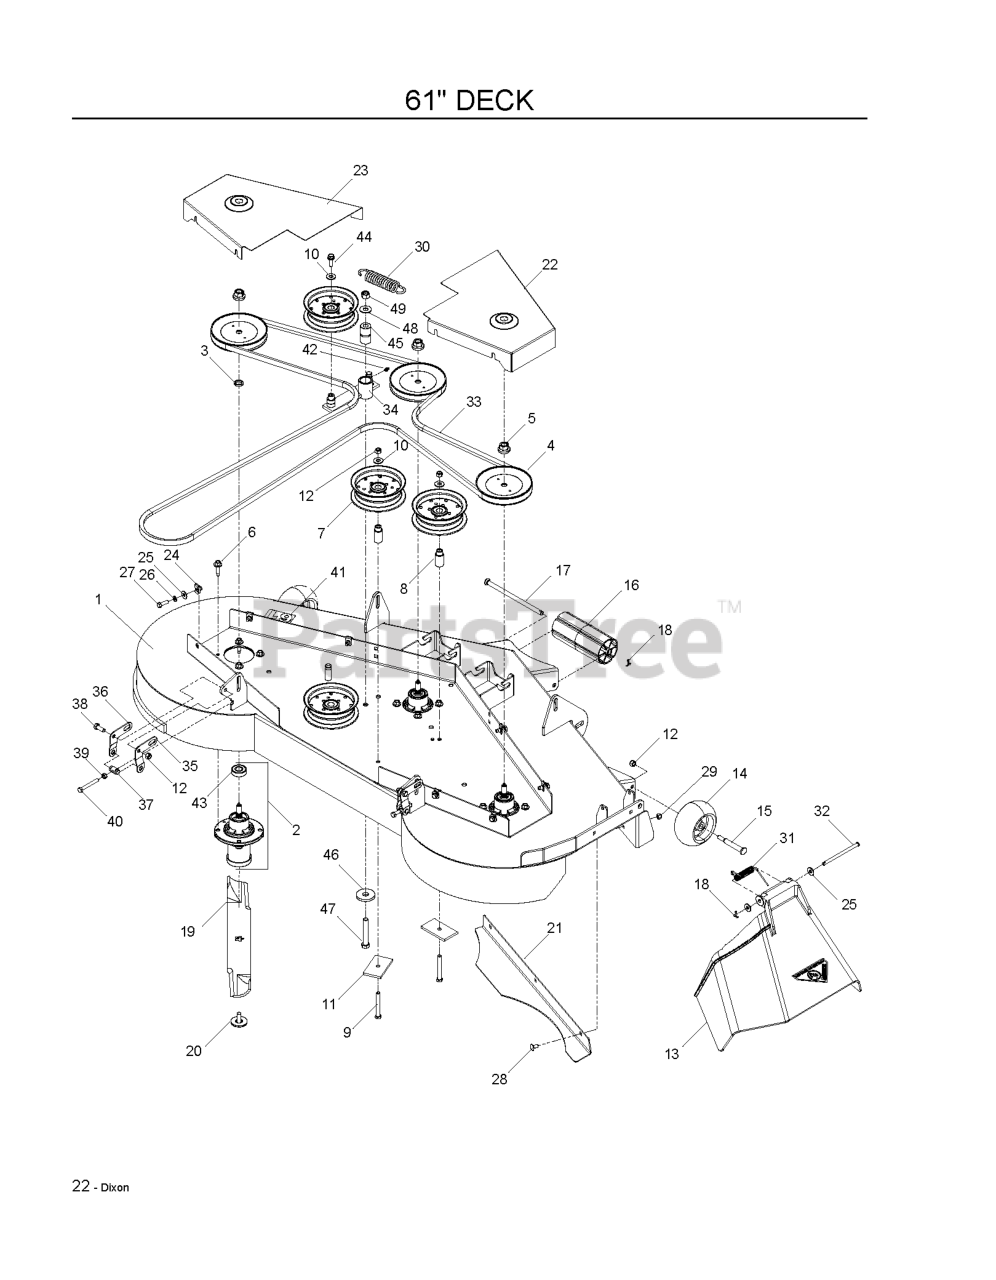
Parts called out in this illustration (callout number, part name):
1	DECK.FAB./DECALS.61.RAM.ULTRA
2	MANDREL.DECK.ASSEMBLY
3	WASHER-SPACER
5	LOCKNUT - 9/16
6	WASHER HEAD SCREW
7	PULLEY, IDLER
8	IDLER BUSHING
9	HCS 3/8C X 3
10	WASHER 3/8 FLAT
11	SUPPORT PLATE
12	NUT 3/8-16 NYLOC
13	DISCHARGE CHUTE 61"
14	GAUGE WHEEL
15	SHOULDER BOLT 1/2X2-5/8 ZD SPE
16	NOSE ROLLER 48"
17	NOSE ROLLER ROD
18	COTTER PIN 1/8 X 3/4
19	BLADE, 21"
20	BLADE BOLT ASSY-7/16" TB REPL
21	CONFINEMENT PLATE 61
22	SHIELD, BELT 61 BLUE RH
23	SHIELD, BELT 61 BLUE LH
24	U-CLIP 5/16-18 NUT RETAINER
25	WASHER 5/16 FLAT
26	WASHER 5/16 LOCK
27	HCS 5/16C X 1
28	CARRIAGE BOLT 5/16C X 5/8"
29	NUT 5/16 NYLOC
31	SPRING - TORSION
32	PIN-CLEVIS 5/16 DIA X 5.19 ZD
33	BELT, DECK
34	IDLER ARM
35	PITCH, ADJUST, RT
36	PITCH, ADJUST, LT
37	TRUNION, PITCH
38	HCS 3/8C X 1
39	NUT 5/16C HEX
40	HCS 5/16-18 X 2 1/2 TPBLT
41	DECAL, 61
42	ZERK
43	BEARING, BALL
44	HCS 3/8C X 1 SERRATED HEAD
45	PIVOT BUSHING
46	WASHER, SUPPORT
47	HCS 1/2C X 3 1/4
48	WASHER 1/2 FLAT
49	NUT 1/2-13 HEX NYLOC ZD
